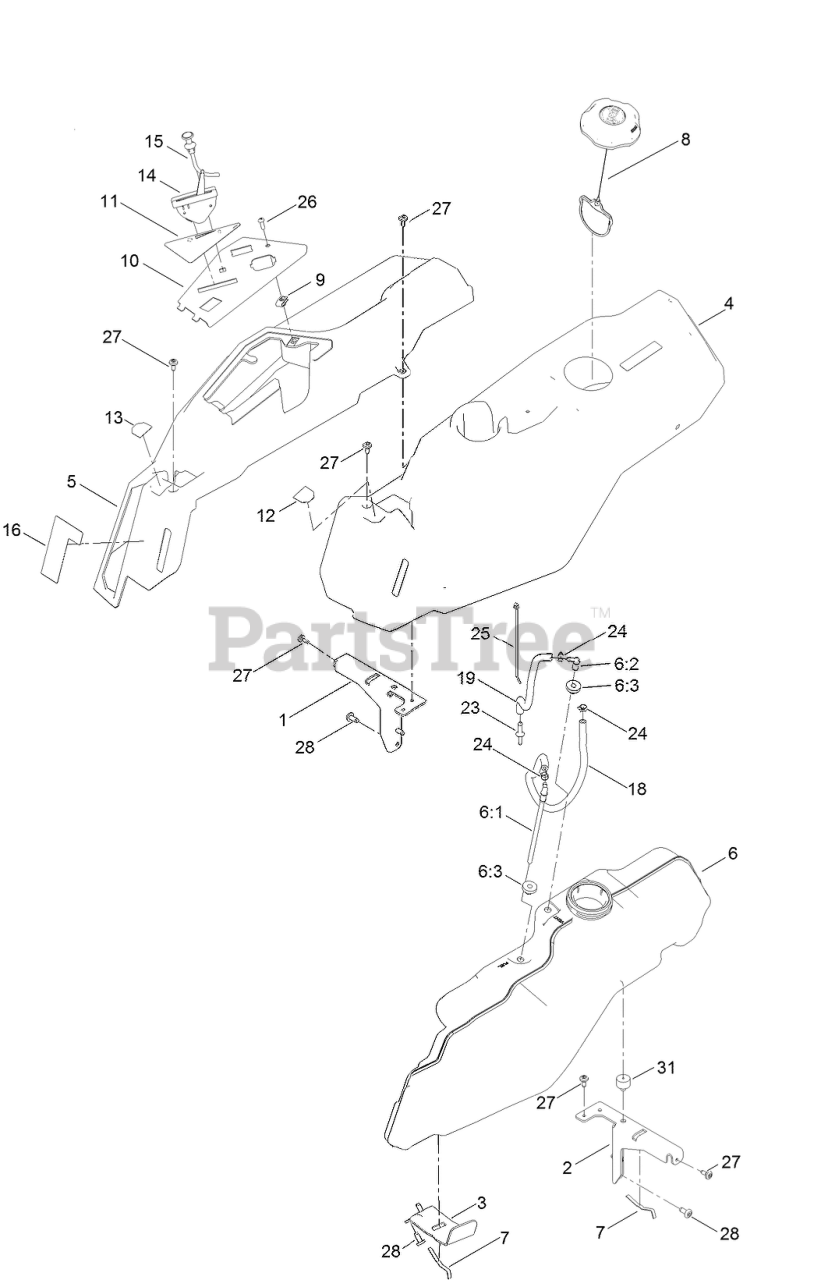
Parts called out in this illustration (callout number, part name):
1	SUPPORT-POD, RH
2	SUPPORT-POD, LH
3	SUPPORT-TANK, FUEL
4	POD-LH
5	POD-RH
6	FUEL TANK ASM
6:1	CONNECTOR-ELBOW, 90 DEG
6:2	FITTING-PLASTIC
6:3	BUSHING
7	SPRING
8	CAP-FUEL, RATCHETING
10	PANEL - CONTROL
11	DECAL-PANEL, CONTROL
12	DECAL-CONTROL LEVER, LH
13	DECAL-CONTROL LEVER, RH
14	CABLE-THROTTLE
15	CABLE-CHOKE
16	DECAL-SMART SPEED
18	HOSE-FUEL
19	HOSE-FUEL
23	ADAPTOR-ORIFICE
24	CLAMP-HOSE
25	TIE-CABLE
26	SCREW-PRH
27	SCREW-SHOULDER
31	BUMPER-GROMMET
